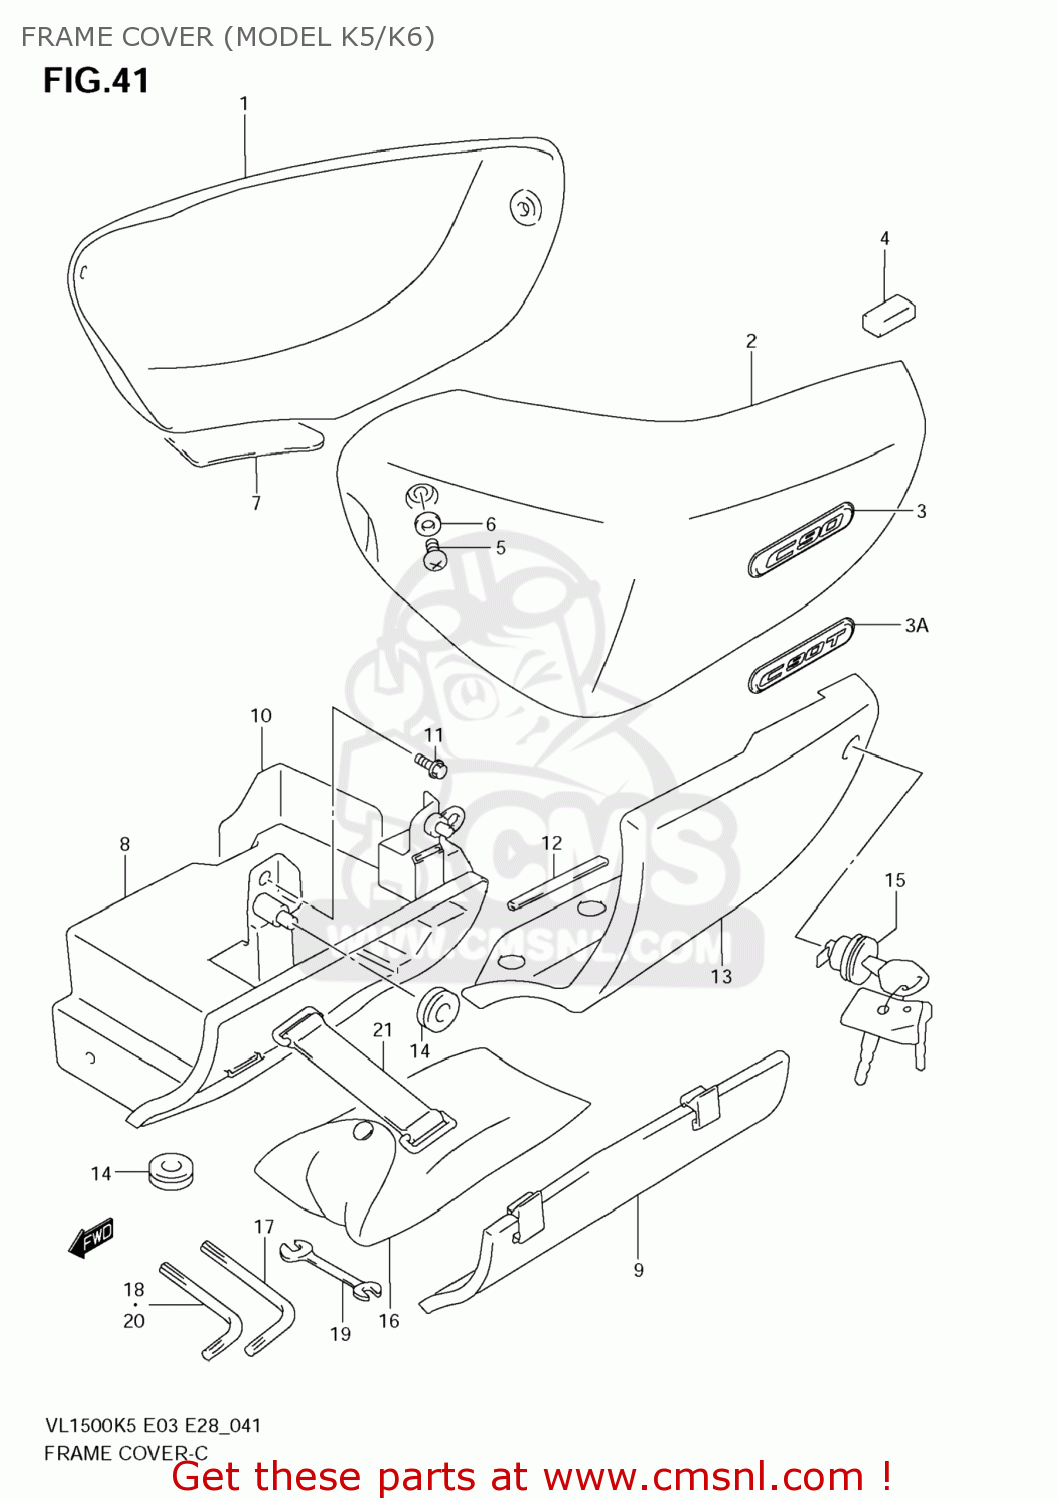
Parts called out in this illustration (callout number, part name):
1	COVER,FRAME,R(BLUE)
2	COVER,FRAME,L(BLUE)
3	EMBLEM,C90
3A	EMBLEM,C90T
4	CUSHION,FRAME COVER
5	SCREW(6X16)
6	WASHER(6.5X15X1.0)
7	SHIELD,FRAME COVER,R
8	BODY,TOOL HOLDER
9	CAP,TOOL HOLDER
10	SHIELD,TOOL HOLDER BODY
11	BOLT(6X16)
12	MOLDING,FRAME COVER,L
13	COVER,TOOL HOLDER
14	CUSHION
15	LOCK SET,COVER
16	TOOL ASSY
17	HEXAGON SPANNER,12
18	SPANNER,HEXAGON(4)
19	OPEN SPANNER(8X10)
20	HEXAGON SPANNER,5
21	BAND
